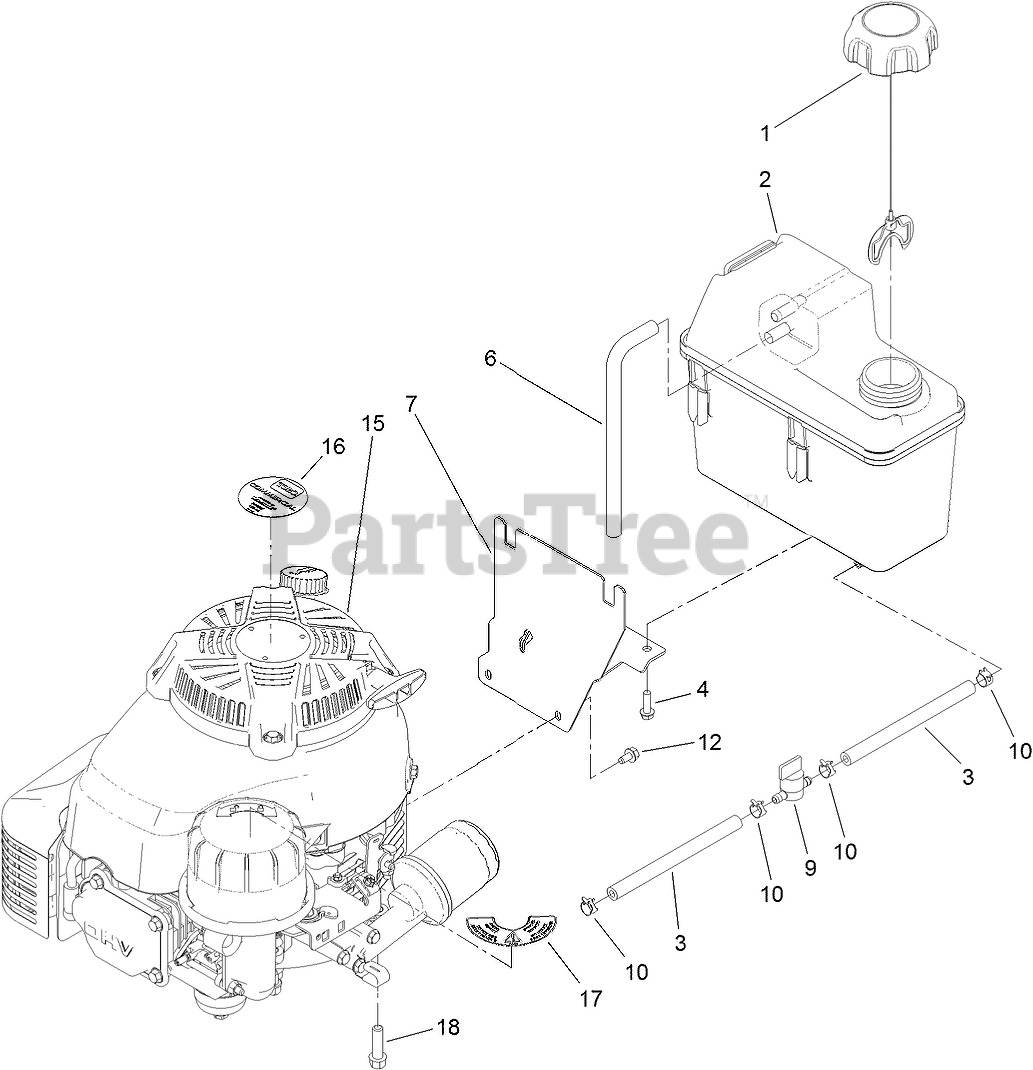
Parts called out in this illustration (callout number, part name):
1	CAP-RATCHET, TETHERED
2	TANK-FUEL
3	HOSE-FUEL
4	SCREW-HWH
6	HOSE-VENT, CANISTER
7	MOUNT-TANK
9	VALVE-FUEL
10	CLAMP-HOSE
12	SCREW-HWH
15	ENGINE-KAWASAKI, FJ180V-BM07-M
18	SCREW-TAPTITE
